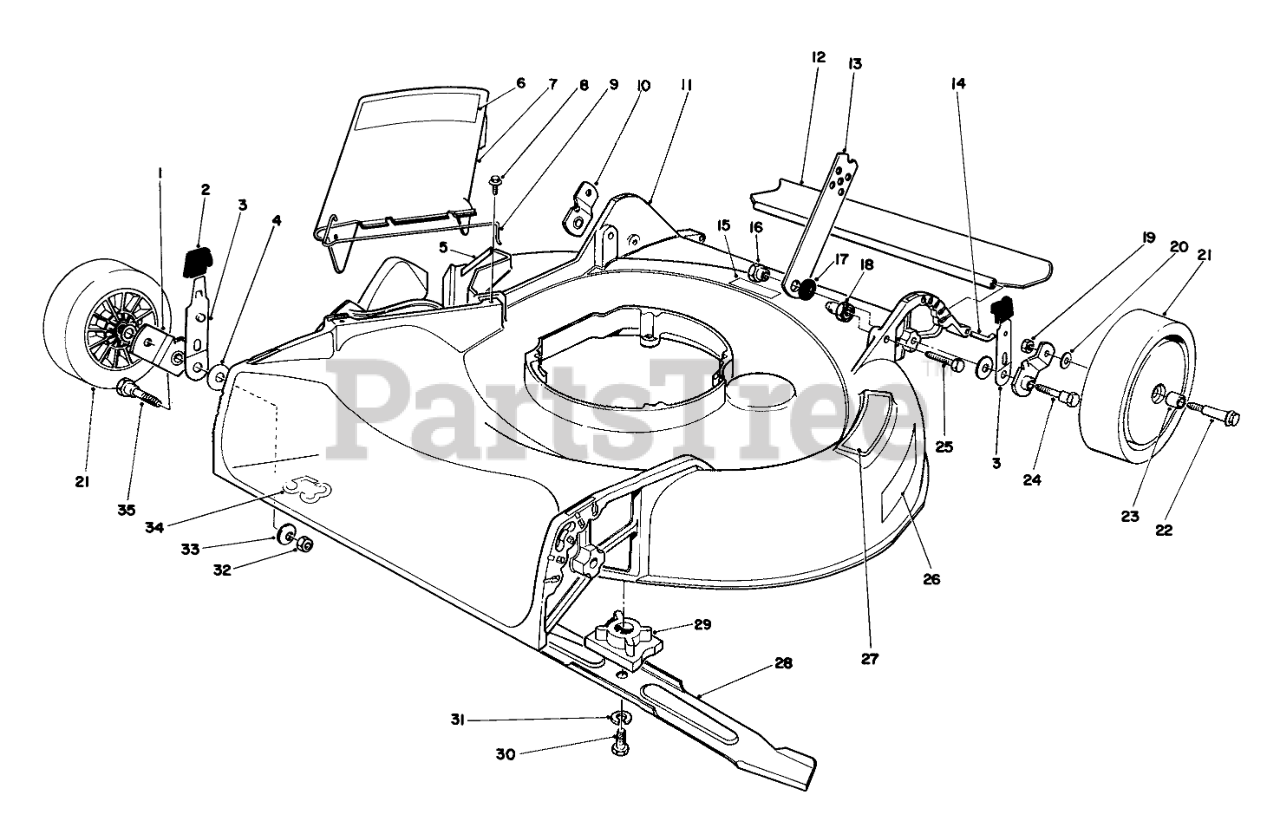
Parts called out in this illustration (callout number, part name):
1	Pivot Arm
2	KNOB-ARM
3	SPRING ARM ASM
4	WASHER-PIVOT
5	DANGER DECAL
6	DECAL - DANGER DEFL
7	Deflector (Incl. Ref. #6)
8	SCREW-HWH
9	SPRING HINGE
10	Pivot Arm
11	Housing (Incl. Ref. #5 & 26)
12	REAR SAFETY SHIELD 21
13	HANDLE LATCH
14	SHIELD ROD
15	Decal
16	HANDLE PIVOT NUT
17	SPACER
18	HANDLE PIVOT NUT
19	Nut
20	WASHER
21	Wheel & Tire Assembly (Incl. Ref. #23)
22	WHEEL BOLT
23	BUSHING
24	PIVOT SCREW
25	SCREW-HH
26	Decal Danger
27	DECAL - STEP PAD INT'L
28	Blade
29	BLADE RETAINER
30	SCREW-HH
31	WASHER-LOCK
32	NUT-LOCK, NI
33	WASHER-BELLEVILLE
34	DECAL - 53
35	5/16-18 PIVOT SCREW
